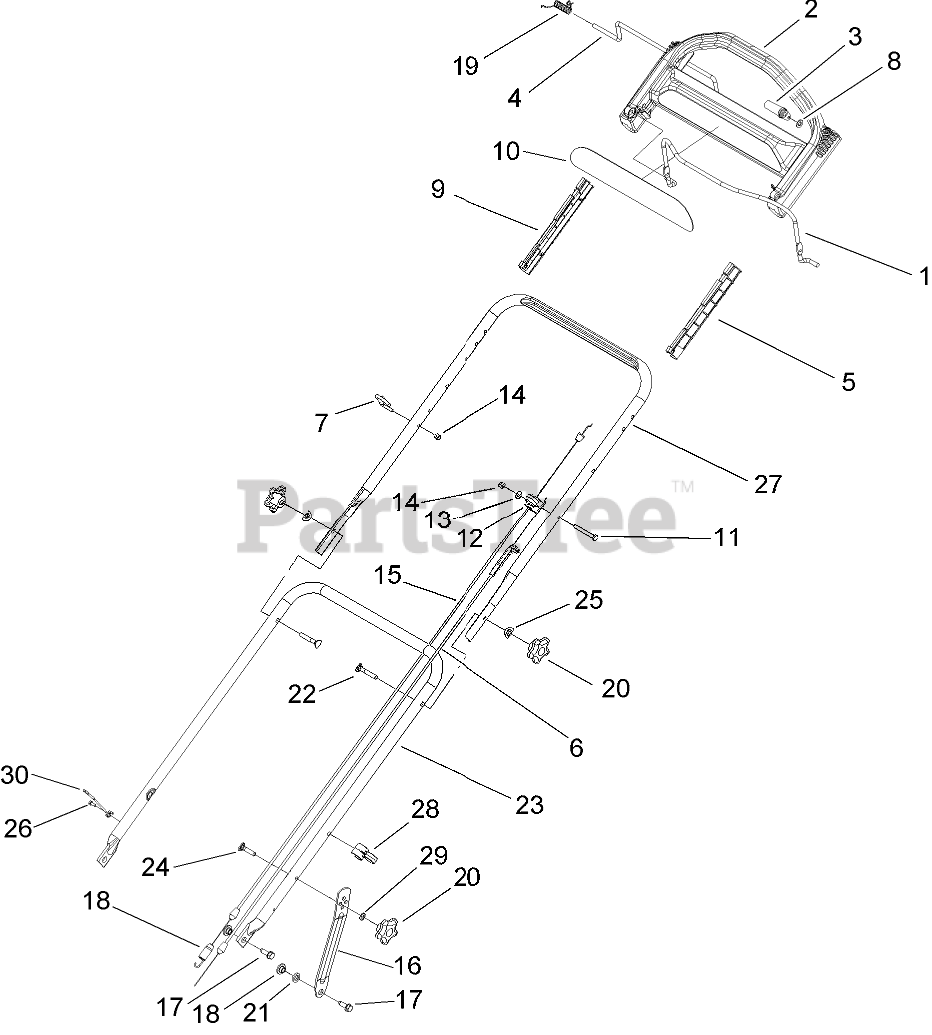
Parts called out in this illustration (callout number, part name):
1	Bail-Brake
2	HANDLE-CONTROL
3	LEVER-TRACTION
4	BAR-CONTROL, TRACTION
5	GUIDE-LH
6	Cable-Brake
7	GUIDE-ROPE
8	WASHER-PLAIN
9	GUIDE-RH
10	DECAL-HANDLE
11	SCREW
12	ANCHOR-CABLE
13	WASHER-FLAT
14	NUT-LOCK, NI
15	CABLE-TRACTION
16	SUPPORT-HANDLE
17	SCREW-HWHTF
18	SPACER-COUPLING
19	Spring-Torsion
20	KNOB-HANDLE
21	WASHER
22	SCREW-HANDLE
23	HANDLE-LOWER
24	SCREW-HANDLE
25	WASHER
26	SCREW-SHWH, THREAD FORMING
27	HANDLE-UPPER
28	Guide-Cable
29	WASHER-LOCK
30	HOOK-ROPE, DISPLACEMENT
